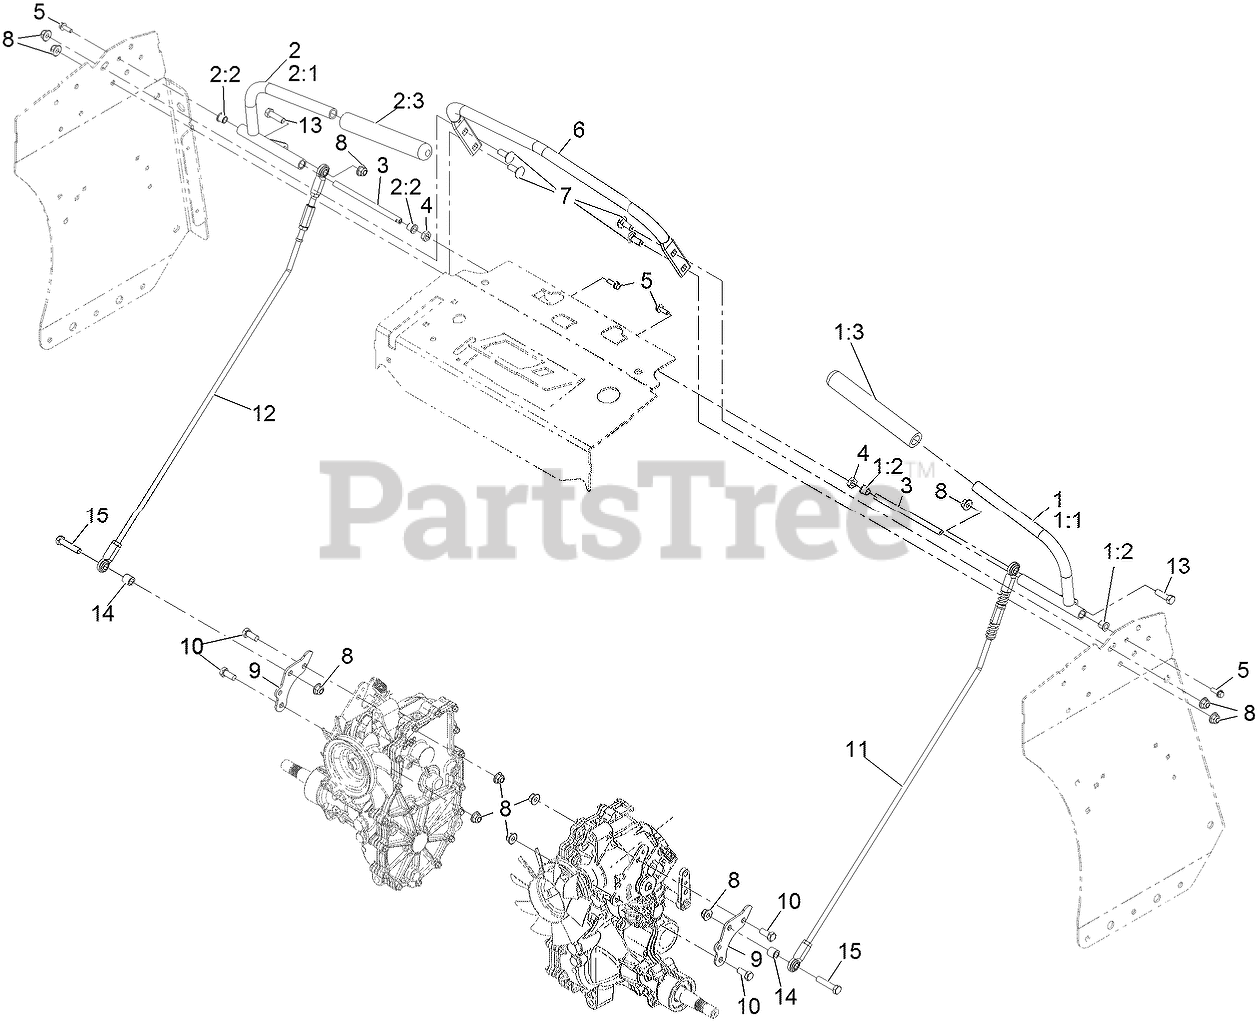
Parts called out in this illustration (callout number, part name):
1	LH Motion Handle ASM
1:1	HANDLE-CONTROL, LH
1:2	BEARING
1:3	GRIP-LEVER, CONTROL
2	RH Motion Handle ASM
2:1	HANDLE-CONTROL, RH
2:2	BEARING
2:3	GRIP-LEVER, CONTROL
3	SHAFT-PIVOT, MOTION CONTROL
4	SPACER-SHAFT, DRIVE LEVER
5	SCREW-HHF
6	BAR, REFERENCE
7	BOLT-CARR
8	NUT-HF, NI
9	ARM-MOTION
10	SCREW-HH
11	LH Motion Linkage ASM
12	RH Motion Linkage ASM
13	SCREW-HH
15	SCREW-HH
